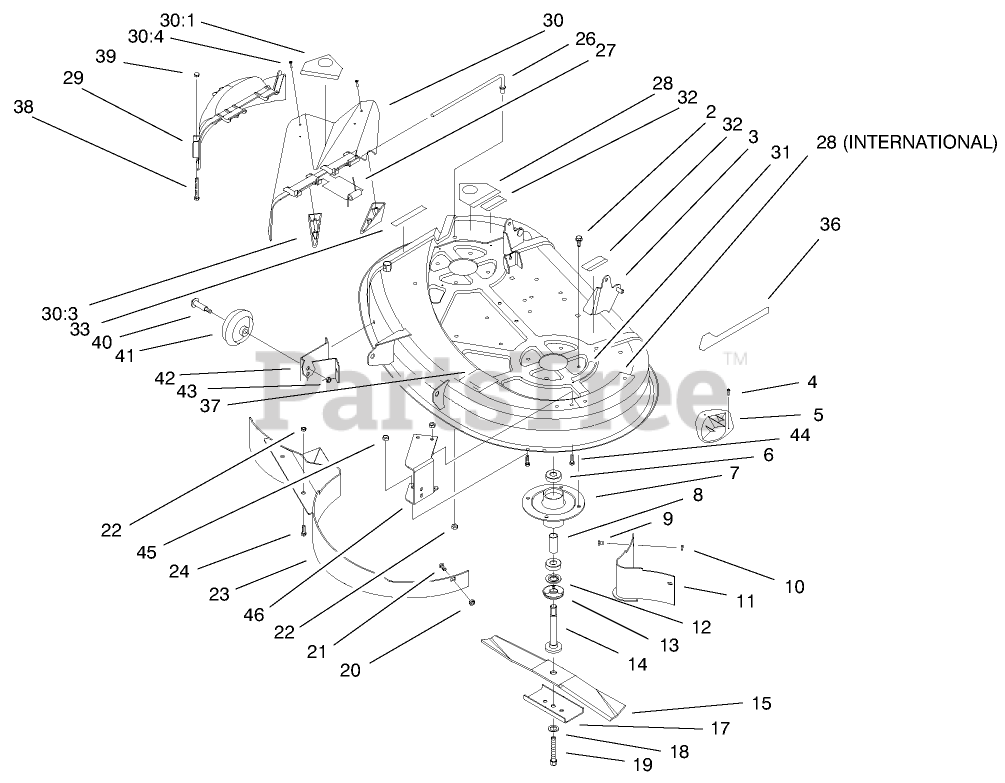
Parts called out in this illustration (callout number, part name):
2	SCREW-TAPTITE
3	DECK ASM
4	SCREW-PPH
5	PLATE-KICKER
6	BEARING-BALL
7	HOUSING-SPINDLE
8	SPACER
9	SCREW-HH
10	NUT-LOCK, NI
11	BAFFLE ASM
12	SPACER
13	SHIELD-BEARING
14	SHAFT-SPINDLE
17	STIFFENER-BLADE
18	WASHER-BELLEVILLE
19	SCREW-HH
20	NUT-LOCK, NI
21	BOLT-CARR
22	NUT-LOCK, NI
23	BAFFLE ASM
24	SCREW-HH
26	ROD-PIVOT
27	SPRING
28	DECAL-DANGER
29	COVER-RECYCLER
30	DEFLECTOR ASM
30:1	DECAL-DANGER
30:3	KICKER
30:4	SCREW-PPH
31	DECAL-DANGER, SHIELD
32	DECAL-WARNING
33	DECAL-DANGER
36	DECAL-RECYCLER DECK 38"
38	SCREW-HH
39	NUT-CAP
40	SCREW-SHOULDER, HWH
41	WHEEL-GAGE
42	BRACKET-WHEEL, RH
43	NUT-LOCK, NI
44	SCREW-HH
45	NUT-LOCK, NI
46	BRACKET-WHEEL, LH
